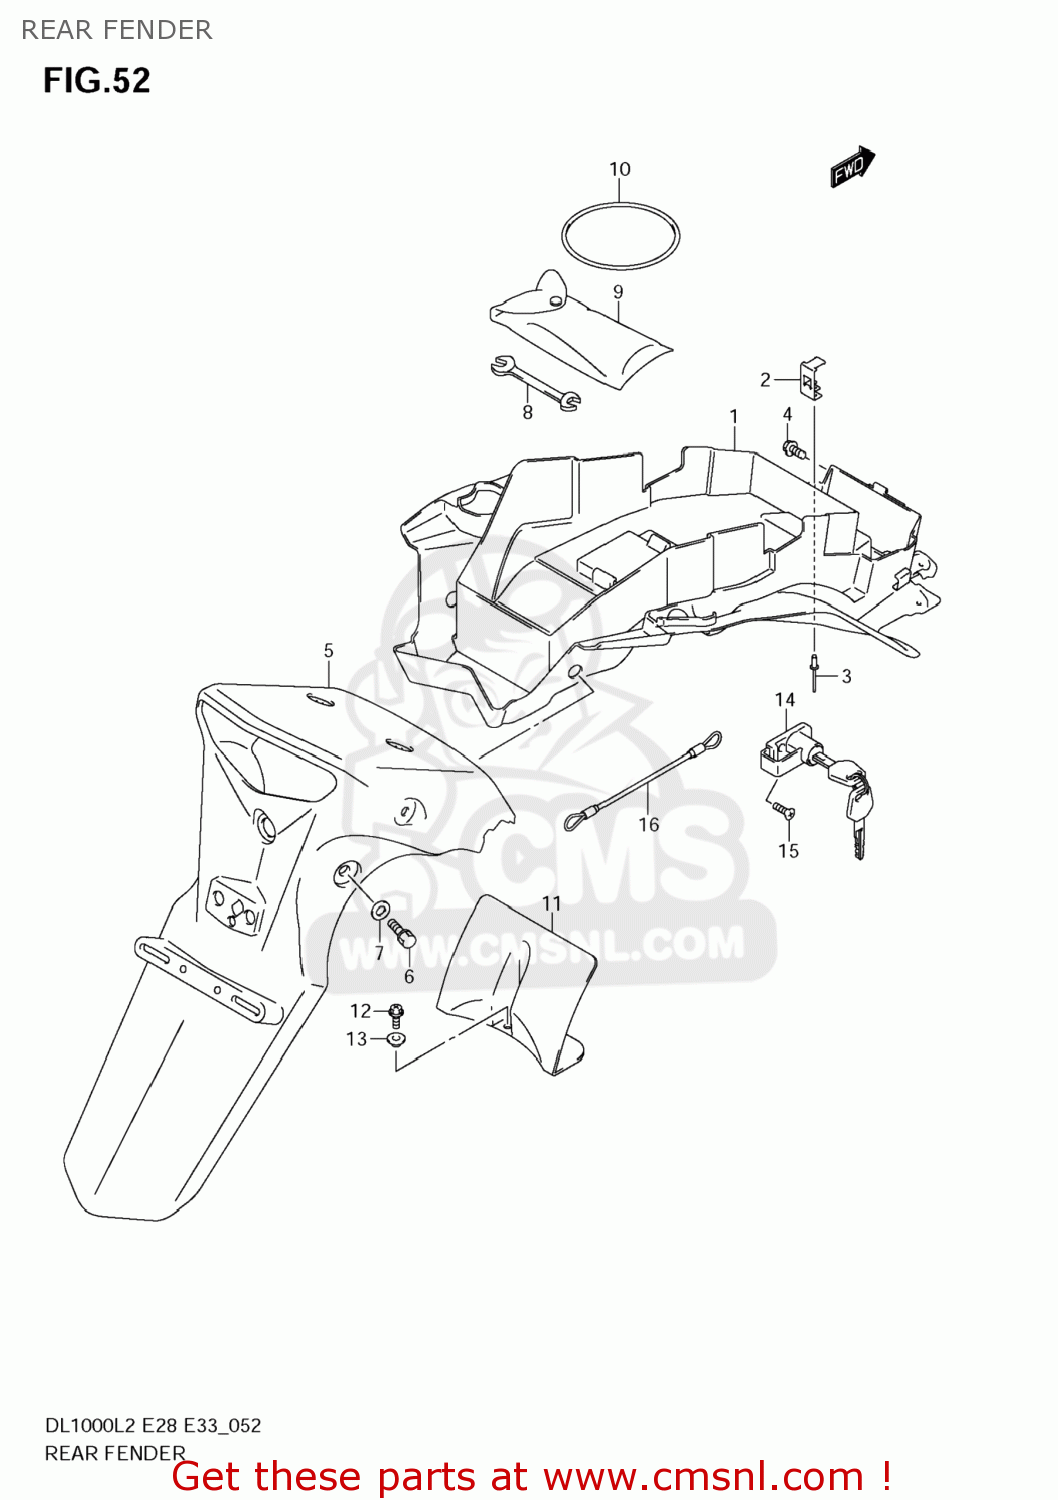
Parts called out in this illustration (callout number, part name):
1	FENDER,RR FR
2	BRACKET,FUEL CUT SENSOR
3	RIVET
4	BOLT(6X12)
5	FENDER,RR RR
6	BOLT
7	WASHER(6.5X18X1.6)
8	OPEN SPANNER(8X10)
9	TOOL ASSY
10	O RING(D:3.5,ID:62.6)
11	MUDGUARD,RR FENDER FR LWR
12	SCREW
13	WASHER
14	LOCK SET,HELMET
15	SCREW
16	CABLE,HELMET LOCK
